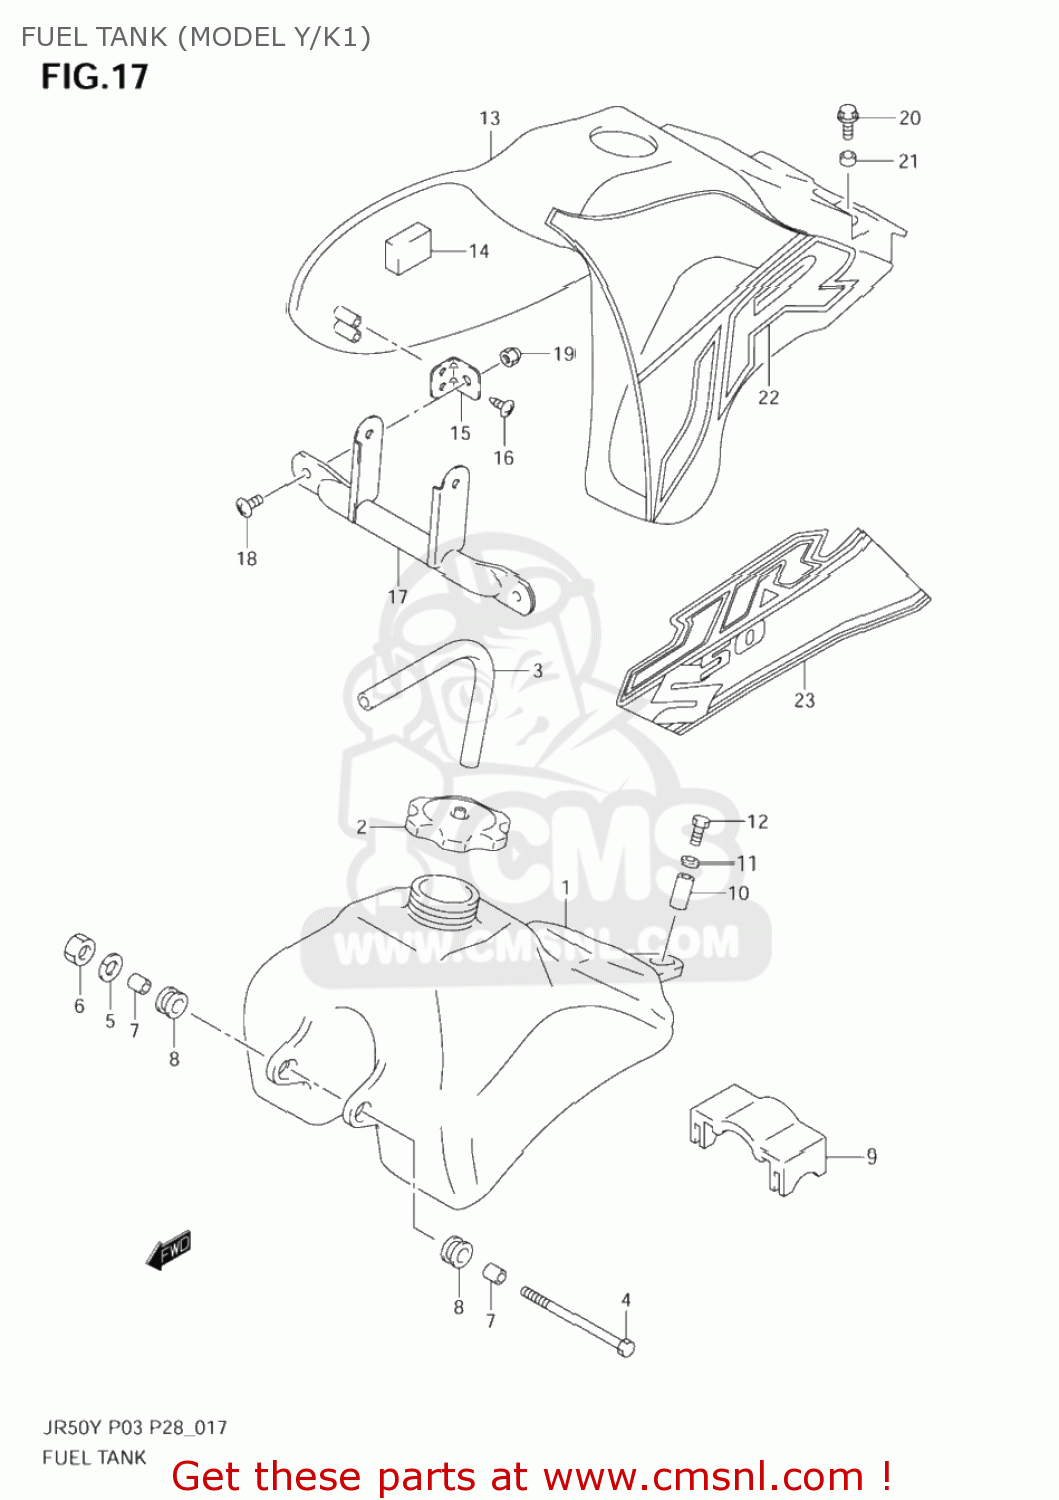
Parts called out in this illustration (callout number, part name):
1	TANK ASSY,FUEL
2	CAP ASSY,FUEL TANK FILLER
3	HOSE(5X8.2X600)
4	BOLT, FRONT
5	LOCK WASHER
6	NUT 6MM
7	SPACER(6.5X10X11.5)
8	CUSHION
9	CUSHION,FUEL TANK UPR
10	SPACER(6.5X9X7.2)
11	WASHER(6.5X18X1)
12	BOLT
13	COVER,FUEL TANK
14	CUSHION,RADIATOR COVER FR
15	BRACKET,FUEL TANK COVER NO.1
16	SCREW
17	BRACKET,FUEL TANK COVER
18	SCREW 6X12
19	NUT
20	SCREW(6X16)
21	SPACER(6.5X10X5)
22	TAPE SET,FUEL TANK COVER
23	TAPE SET,FUEL TANK COVER
